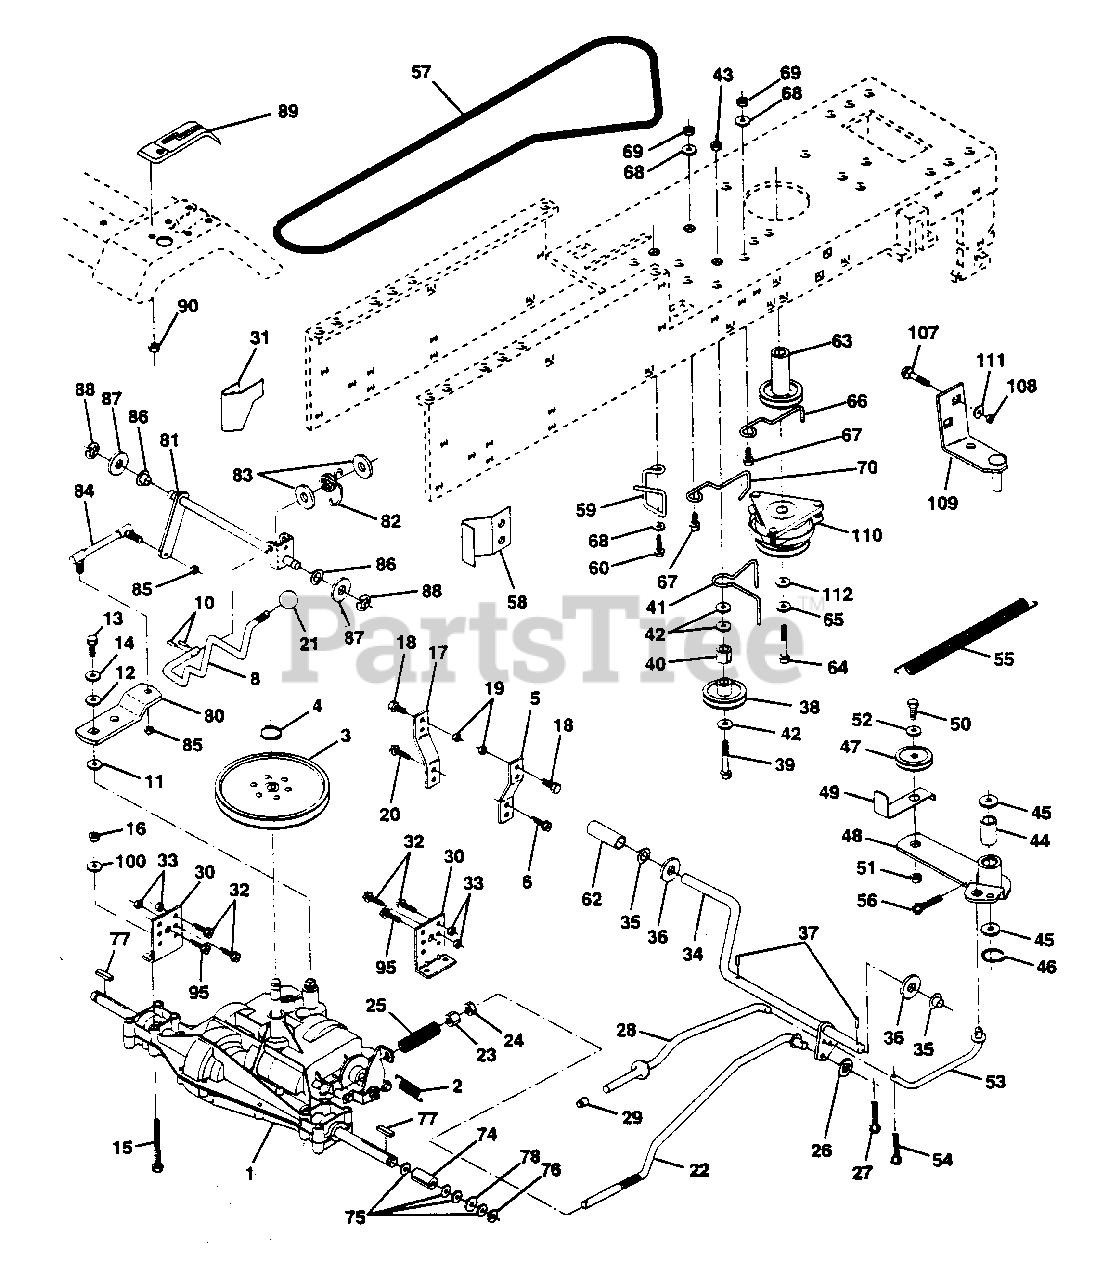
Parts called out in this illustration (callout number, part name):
1	Transaxle 6sp Dana LT Model # 4360-81 (AYP part number)
2	Spring Return Brake T/a Zinc (AYP part number)
3	Pulley Transaxle 20"tires (AYP part number)
4	Ring Retainer # 5100-62 (AYP part number)
5	Strap Torque 30 Degrees (AYP part number)
6	Screw Thdrol 5/16-18 X 3/4 TYT
8	Rod Shifter (AYP part number)
10	Pin Cotter 1/8 X 1 Cad (AYP part number)
11	Washer Plate Shf 388 Sq Hole (AYP part number)
12	Washer 15/32 X 3/4 X 16 Ga (AYP part number)
13	Bolt Fin Hex 1/4-28unfx3/4 Gr8 (AYP part number)
14	Washer Lock Hvy Helical 1/4 (AYP part number)
15	Bolt Fin Hex 5/16-18uncx 2 3/4 (AYP part number)
16	Nut Lock H w/insert 5/16-18 (AYP part number)
17	Strap Torque LT (AYP part number)
18	Bolt Fin Hex 3/8-16unc X 1 Gr. 5 (AYP part number)
19	Nut Lock 3/8-16 Unc (AYP part number)
20	Screw Thdrol 5/16-18 X 3/4 TYT
21	Knob Duckhead 3/8-16unc Blk (AYP part number)
22	Rod Brake Blk Zinc 27 326 (AYP part number)
23	Nut Lock Hex W/wsh 3/8-16unc (AYP part number)
24	Nut Hex Jam 3/8-16 Unc (AYP part number)
25	Spring Rod Brake 2 00 Zinc (AYP part number)
26	Washer 13/32 X 13/16 X 16 Ga (AYP part number)
27	Pin Cotter 1/8 X 3/4 Cad (AYP part number)
28	Rod Brake Parking 14 500 (AYP part number)
29	Cap Brake Parking Black (AYP part number)
30	Bracket Mtg Transaxle (AYP part number)
31	Keeper Belt LH LT 14 Ga (AYP part number)
32	Bolt Hex Hd 5/16-18unc X 3/4 (AYP part number)
33	Nut Lock 5/16-18 (AYP part number)
34	Shaft Asm Pedal Foot 1 930 (AYP part number)
35	Bearing Nylon Blk 629 Id (AYP part number)
36	Washer 21/32 X 1 X 16 Ga (AYP part number)
37	Pin Roll 3/16 X 1" (AYP part number)
38	Pulley Idler Flat (AYP part number)
39	Bolt Fin Hex 3/8-16unc X 2-3/4 (AYP part number)
40	Spacer Split 395 X 59 Bzp (AYP part number)
41	Keeper Belt Retainer (AYP part number)
42	Washer 13/32 X 13/16 X 12 Ga (AYP part number)
43	Nut Lock 3/8-16 Unc (AYP part number)
44	Bearing Nyl 503 X 628 X 1 25 (AYP part number)
45	Washer Hardened (AYP part number)
46	Ring Klip #t5304-50 (AYP part number)
47	Pulley Idler V Groove Plastic
48	Bellcrank Asm Clutch (AYP part number)
49	Retainer Belt Style Spring (AYP part number)
50	Bolt Hex Hd 3/8-16unc X 1-1/2 (AYP part number)
51	Nut Crownlock 3/8-16 Unc
52	Washer 13/32 X 13/16 X 16 Ga (AYP part number)
53	Link Clutch 7 66 (AYP part number)
54	Pin Cotter 1/8 X 3/4 Cad (AYP part number)
55	Spring Return Clutch 6 75 (AYP part number)
56	Pin Cotter 1/8 X 3/4 Cad (AYP part number)
57	V-Belt Ground Drive 95 25 42" (AYP part number)
58	Keeper Belt RH LT Pnt/zinc 16g (AYP part number)
59	Keeper Belt Chassis Span Ctr (AYP part number)
60	Screw Thdrol 3/8-16x3/4 Ty-tt (AYP part number)
62	Cover Pedal Blk Round (AYP part number)
63	Engine Pulley LT/YT (AYP part number)
64	Bolt, Hex 7/16-20 x 4-1/4 (AYP part number)
65	Washer Lock Hvy Hlcl Spr 7/16 (AYP part number)
66	Keeper Belt Engine LH LT (AYP part number)
67	Bolt Fin Hex 3/8-16unc X 1 (AYP part number)
68	Washer 13/32 X 13/16 X 12 Ga (AYP part number)
69	Nut Crownlock 3/8-16 Unc
70	Keeper Belt Engine BZP Zinc (AYP part number)
74	Spacer Split (AYP part number)
75	Washer 25/32 X 1 1/4 X 16 Ga (AYP part number)
76	E-ring #5133-75 (AYP part number)
77	Key Square 2 0 X 1845/ 1865 (AYP part number)
78	Washer 25/32 X 1-5/8 X 16 Ga (AYP part number)
80	Arm Shift Transaxle (AYP part number)
81	Shaft Asm Cross 20"t 42"deck (AYP part number)
82	Spring Torsion T/a (AYP part number)
83	Washer 17/32 X 3/4 X 16 Ga (AYP part number)
84	Rod Tie Shift Adj Ball (AYP part number)
85	Nut Nylock 1/4-28 (AYP part number)
86	Bushing Rod Strg 629/632 Id (AYP part number)
87	Washer 21/32 X 1-1/4 X 16 Ga (AYP part number)
88	Ring Klip #5304-62 (AYP part number)
89	Console Shift 6sp W/ign LT (AYP part number)
90	Nut Self-thd wsh-hd 1/4 zinc (AYP part number)
95	Screw Thdrol 3/8-16 x 3/4 (AYP part number)
100	Washer 11/32 x 3/4 x 16 Ga. (AYP part number)
107	Bolt, Carriage 5/16-18 x 3/4
108	Nut Crownlock 5/16 - 18
109	Bracket Asm. Clutch (AYP part number)
110	Clutch Electric (AYP part number)
111	Washer 11/32 x 5/8 x 12 Ga. (AYP part number)
112	Washer 1-1/2 OD X 15/32 ID X .250 (AYP part number)
